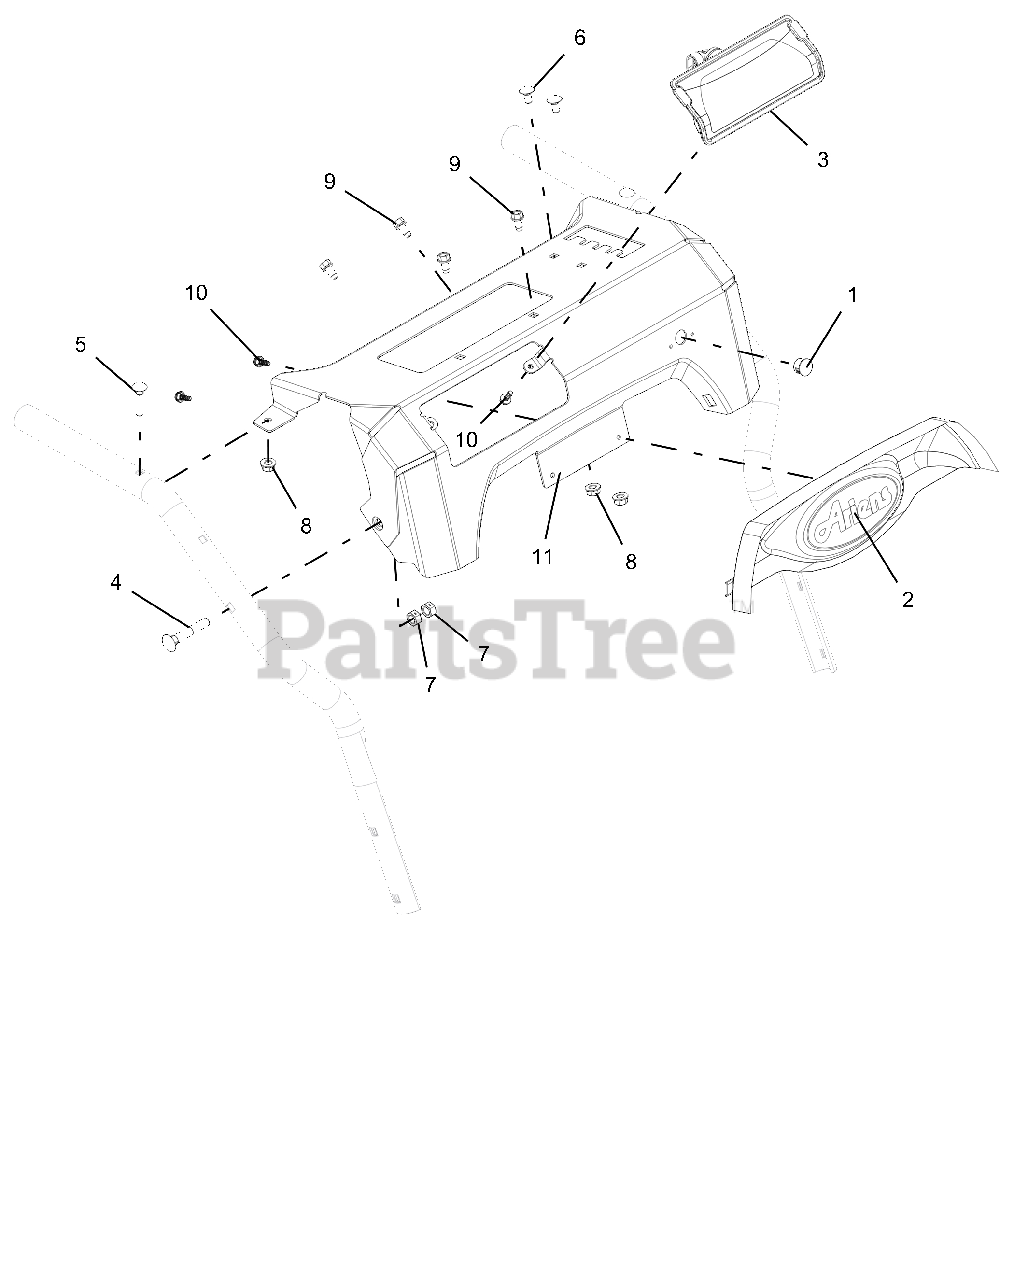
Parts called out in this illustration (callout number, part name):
1	HOLE PLUG, PLASTIC .56 HOLE
2	DASH BEZEL, ARIENS LOGO - COMP
3	HEADLIGHT ASY, HALO 20W 2SHOT
4	BLT-RDHDXLSQNK .31-18X2.0 G5YZ
5	BLT-RDHDXLSQNK.25-20X1.25 G5ZC
6	@BLT-RDHDSQNK .25-20X.50 G5YZ
7	@NUT-LK-CTR .31-18 YWZC
8	@NUT-LK-TOP-FLG .25-20 YWZC
9	SCR-TAP .25-20X.50 HWH TR YWZ
10	SCR-TAP #10X.50 BOSS INDHXHD
11	CTRL PANEL W/DECAL, ARIENS REM
